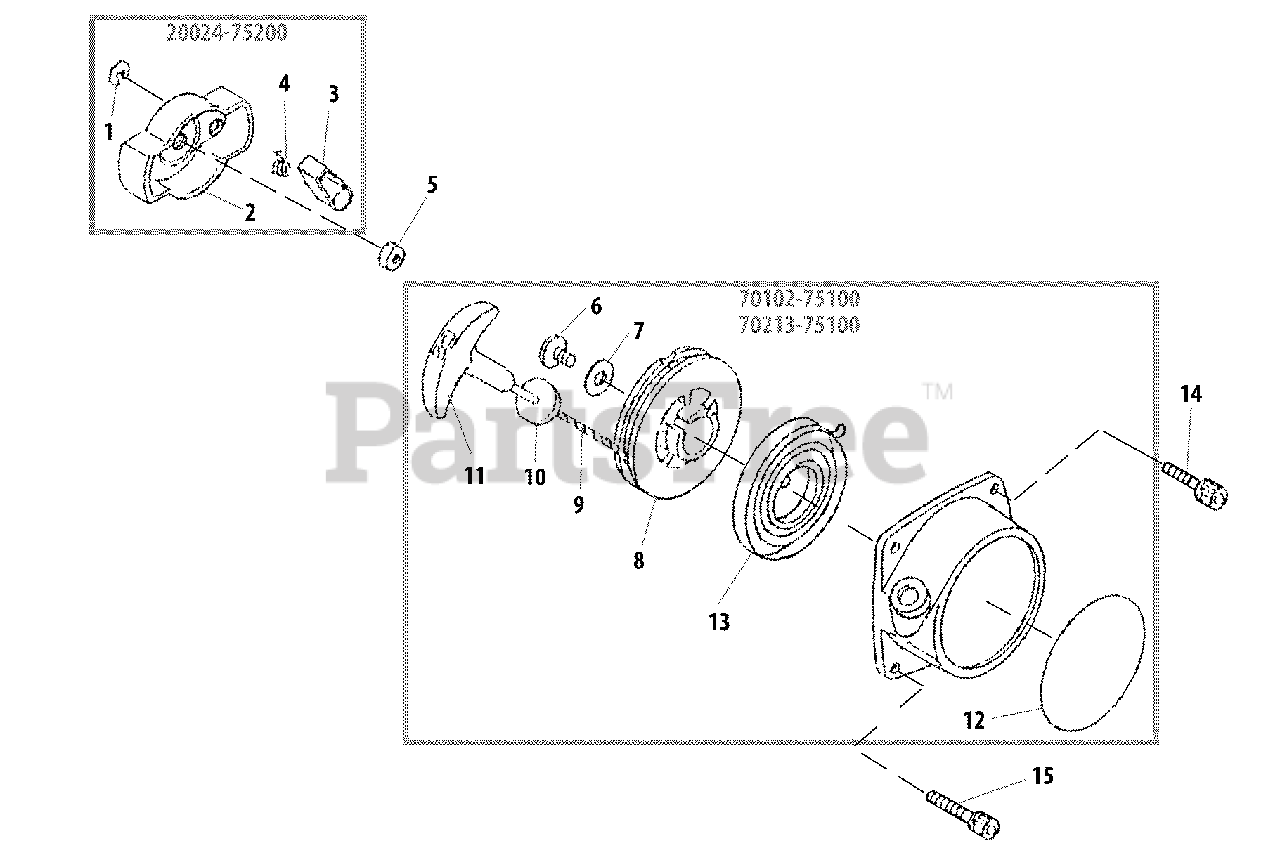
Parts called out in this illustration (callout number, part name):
1	RING, RETAINING
2	CASE, PAWL
3	PAWL, STARTER
4	SPRING, RETURN
5	NUT
6	SCREW
7	WASHER
8	REEL, ROPE
9	ROPE
10	GUIDE, ROPE
11	GRIP, STARTER
12	LABEL
13	SPRING
14	SCREW - 5X20
15	SCREW - 5X25
A	STARTER PAWL ASSY
A	STARTER ASSY
A	STARTER ASSY - BLUE
